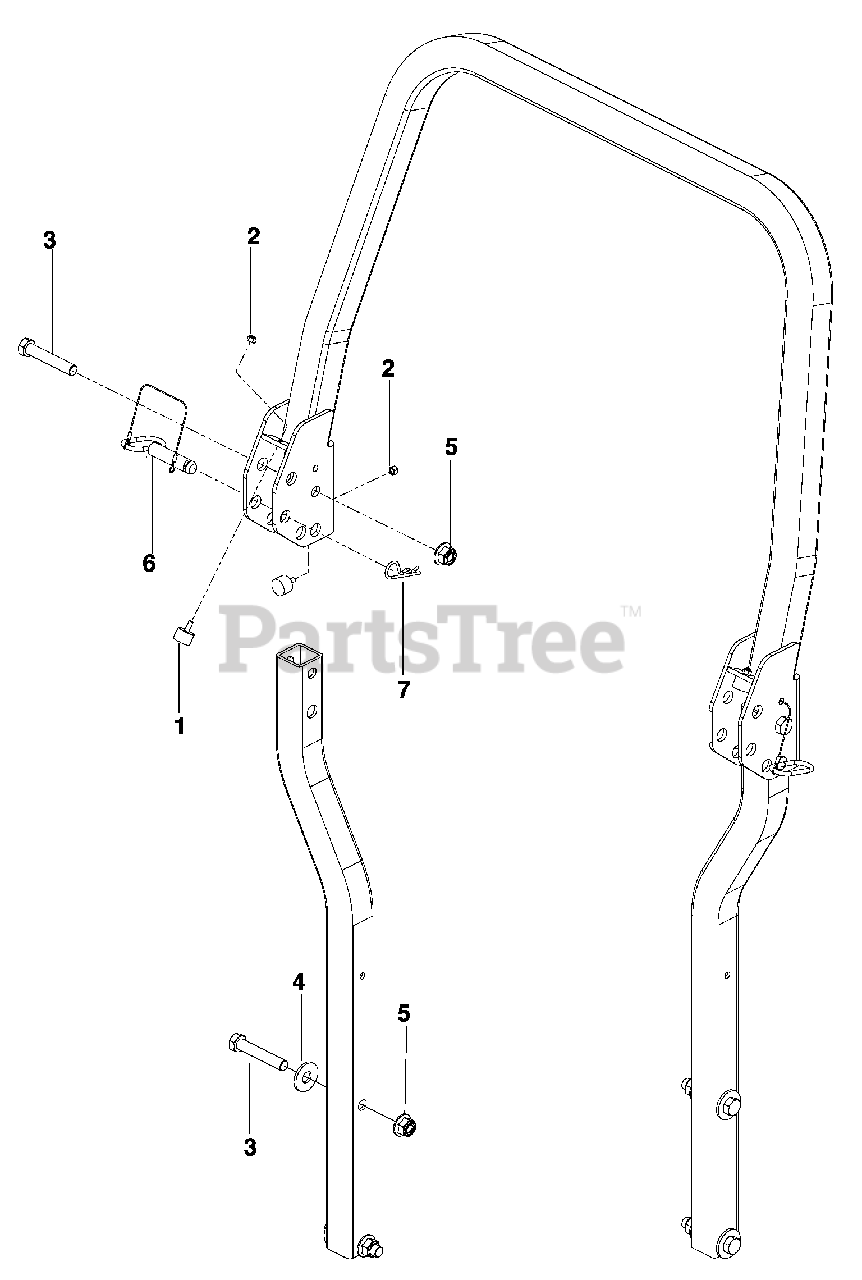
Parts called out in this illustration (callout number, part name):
1	BUMPER, MALE STUD ¼-20
2	NUT ¼-20 HEX NYLOC
3	HCS 5/8-18 x 3½
4	WASHER 5/8 STD FLAT
5	NUT 5/8-11 FLG NYLOC
6	LATCH PIN w/ LANYARD
